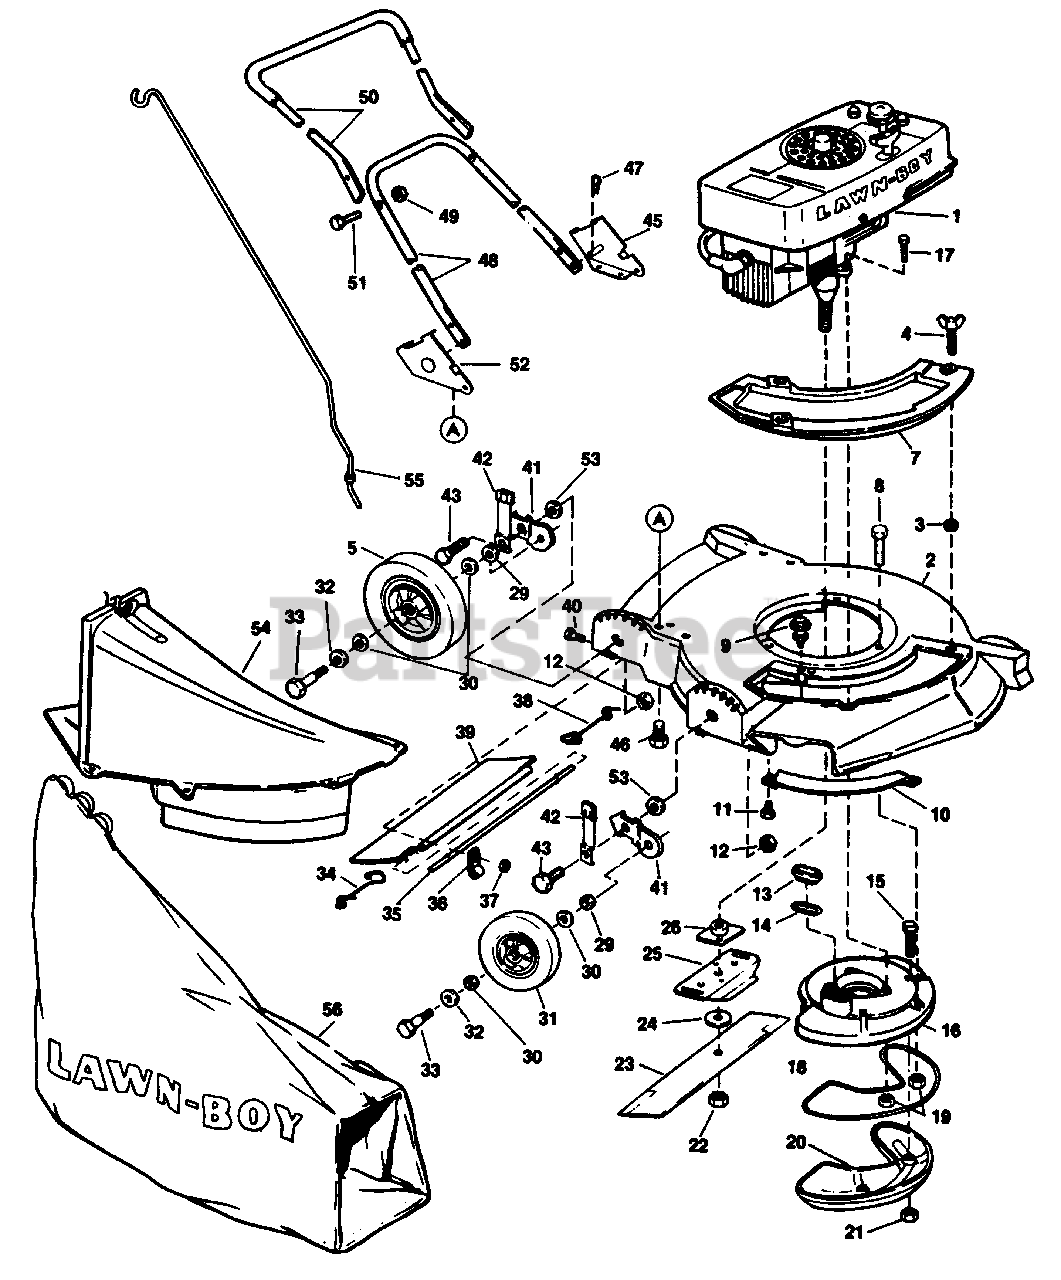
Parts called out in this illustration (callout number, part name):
1	See Page 34 for Engine, Magneto and Carburetor Parts List. See Note #2 at bottom of this page.
2	Housing & Cover Plate-21"
3	Grommet (Also Included in 679652 19" Housing)
4	Screw (Also for 19" Models)
5	Wheel & Tire-8"
6	Bolt-Rear Wheel
7	Cover-Chute (19" & 21" Models)
8	Screw-Muffler Plate to Housing
9	Bolt
10	Toe Bar-19" Models
10	Toe Bar-21" Models
11	Screw
13	Sleeve-Muffler Gasket
14	Gasket-Exhaust
15	Screw-Muffler to Muffler Plate
18	Gasket-Muffler
20	Muffler
21	Nut-Muffler
22	Nut-Blade
23	Blade-21"
23	Blade-19"
24	Washer (21" Models Only)
25	Stiffener-Blade
26	Collar & Plate Assembly
30	Felt Washer
31	Wheel & Tire-6"
32	Washer-Wheel Bolt Head
33	Bolt-Shoulder, Wheel-Front
34	Spring-R.H.
35	Rod-19" Models
35	Rod-21" Models
38	Spring-L.H.
39	Shield-19" Models
39	Shield-21" Models
41	Wheel Hgt. Adj. Bracket
42	Knob & Spray Ay.
43	Bolt-Shoulder
45	Bracket-Handle-Left
47	Hairpin
48	Handle-Bottom
49	Nut-Handle
50	Handle-Top
51	Screw-Handle
52	Bracket-Handle-Right
54	Chute
55	Rod
56	Grass Bag
